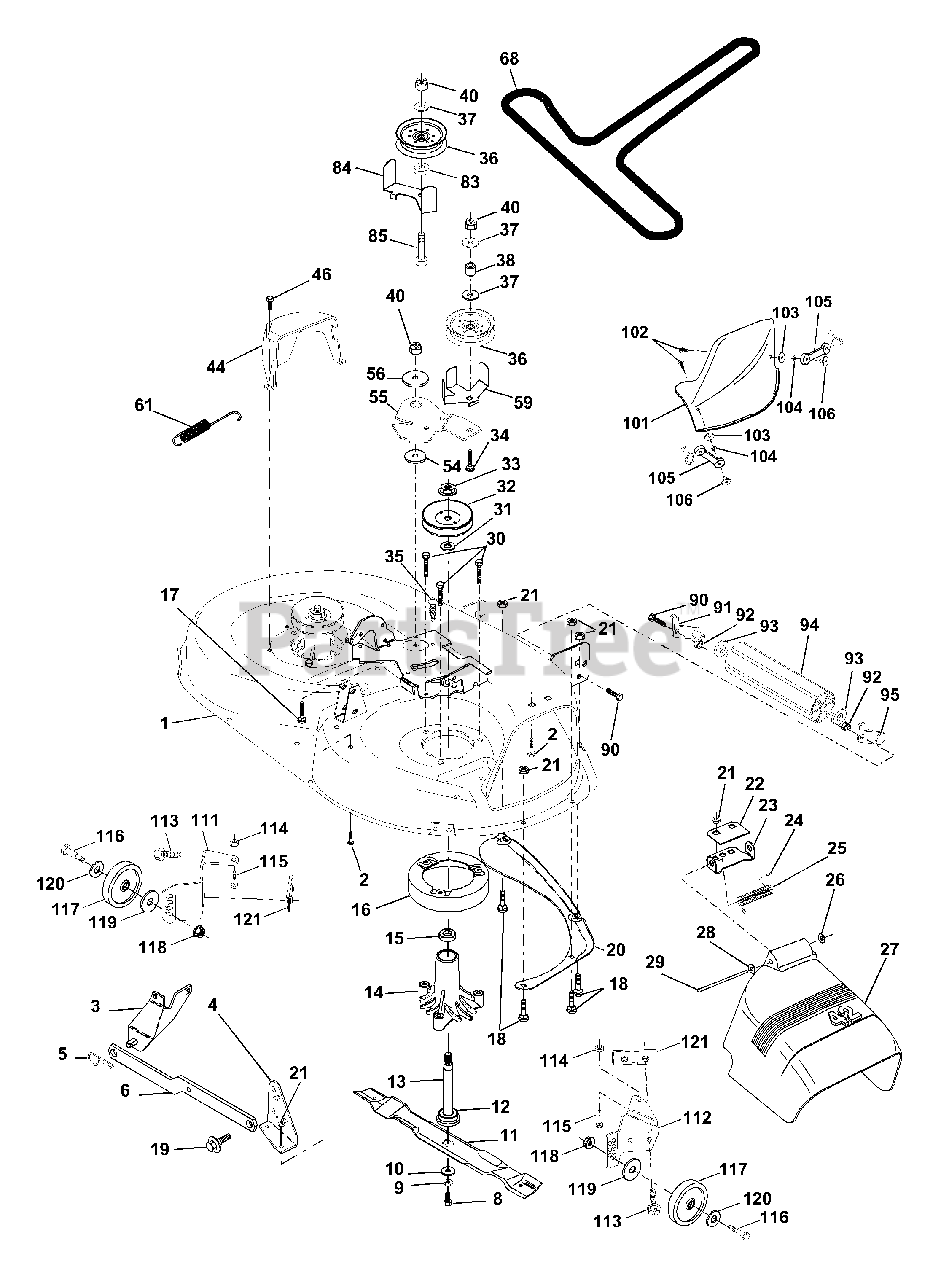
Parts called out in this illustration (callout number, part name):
1	Deck Asm MWR 42"weldment
2	Bolt Rdhd Sqnk 5/16-18unc X3/4
3	Bracket Asm Fr Sway Bar 38/42
4	Bracket Asm Deck 42"sway Bar
5	Retainer Spring
6	Arm Suspension Rear
8	Bolt 3/8-24x1 25 Gr8 Patched
9	Washer Lock Hvy 3/8 Unplated
10	Washer Hard Blade Mower Vented
11	Blade Mower Mulching 42"
12	Bearing Ball #6204 (Mandrel)
13	Shaft Asm W/lower Bearing
14	Housing Mandrel Vented(machd)
15	Bearing Ball Mandrel
16	Stripper Mower Vented
17	Bolt Carriage 3/8-16 X 1-1/4
18	Bolt Carr 5/16-18 X 5/8
19	Bolt Shoulder
20	Baffle Vortex 42
21	Nut Crown Lock 5/16-18
22	Stiffener Bracket 42"deck
23	Bracket Deflector Mower 42"
24	Cap Sleeve 80x 112 Blk Mower
25	Spring Torsion Deflector 2 52
26	Nut Push Phos & Oil
27	Shield Deflector Mower 42" Blk
28	Washer 11/32 X 5/8 X 16 Ga
29	Rod Hinge 42"6 75 Wlg
30	Screw Thdrol Hex Hd Zinc Mwr.
31	Washer Spacer Mower Vented
32	Pulley Mandrel 42"
33	Nut 9/16top Lock Flng Cntr
34	Bolt Rdhd 3/8-16uncx2-3/4 Gr5
35	Fastner Christmas Tree
36	Pulley Idler Flat 3 060
37	Washer 13/32 X 13/16 X 16 Ga
38	Spacer Spring Stop Idler
40	Nut Crownlock 3/8-16 Unc
44	Guard Mandrel LH Black
46	Screw Thdrol 1/4-20x5/8
54	Washer Hardened
55	Arm Idler 42"mower LT/YT
56	Spacer Retainer Pm Mower
59	Guard, Belt
61	Spring Ext. Elect
68	V-Belt Mower
83	Washer Sintered
84	Keeper Belt Idler Fixed
85	Bolt Carriage 3/8-16 x 2-1/2 Gr. 5
90	Bolt Fin Hex 3/8-16unc X 1
91	Bracket Asm Noseroller LH
92	Nut Lock 3/8-16 Unc
93	Washer 17/32 X 7/8 X 16 Ga
94	Roller Nose 38 & 42
95	Bracket Asm Noseroller RH
101	Cover Mulching 42" Black
102	Screw
103	Washer #10
104	Washer Lock #10
105	Latch Asm. Bagger
106	Nut Weld
111	Bracket Wheel Gauge Lh 42" Deck
112	Bracket Wheel Gauge Rh 42" Deck
113	Screw Thdrol 5/16-18 x 3/4
114	Nut Keps 5/16-18 UNC
115	Bolt Carriage 5/16-Unc x 1/2
116	Bolt Shld "A" 2.41 "B" 1.66
117	Wheel Gauge blk. 4.93
118	Nut Centerlock 3/8-16 UNC
119	Washer 3/8 x 7/8 x 14 Ga.
120	Washer 17/32 x 15/16 x 12 Ga.
121	Bracket Extruded Gauge Wheel
